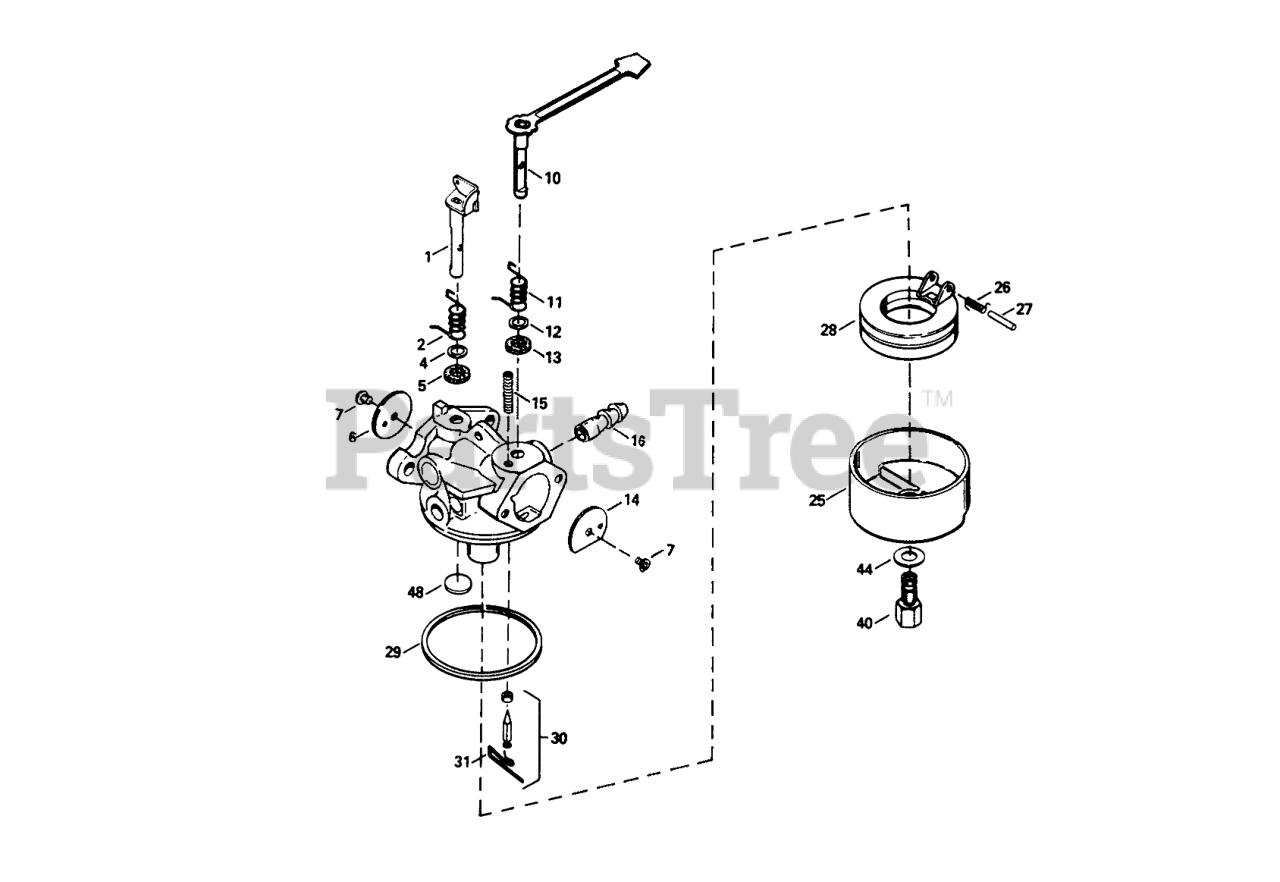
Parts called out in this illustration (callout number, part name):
1	Throttle Shaft & Lever Asm.
2	Spring-Trottle, Return
4	Washer-Seal, Dust
5	Seal-Dust
6	Shutter-Throttle
7	Screw-Shutter
10	Choke Shaft and Lever ASM
14	Shutter-choke
15	Spring-Positioning, Choke
16	Fitting-Fuel
25	Bowl Float
26	Spring-Float, Dampening
27	Shaft-Float
28	Float
29	O Ring-Bowl, Float
30	Inlet Needle, Seat & Clip (Incl. ref. #3)
31	Clip-Spring
40	Nut-Float Bowl
44	Gasket-Bowl
48	Plug-Welch, Atmospheric Vent
